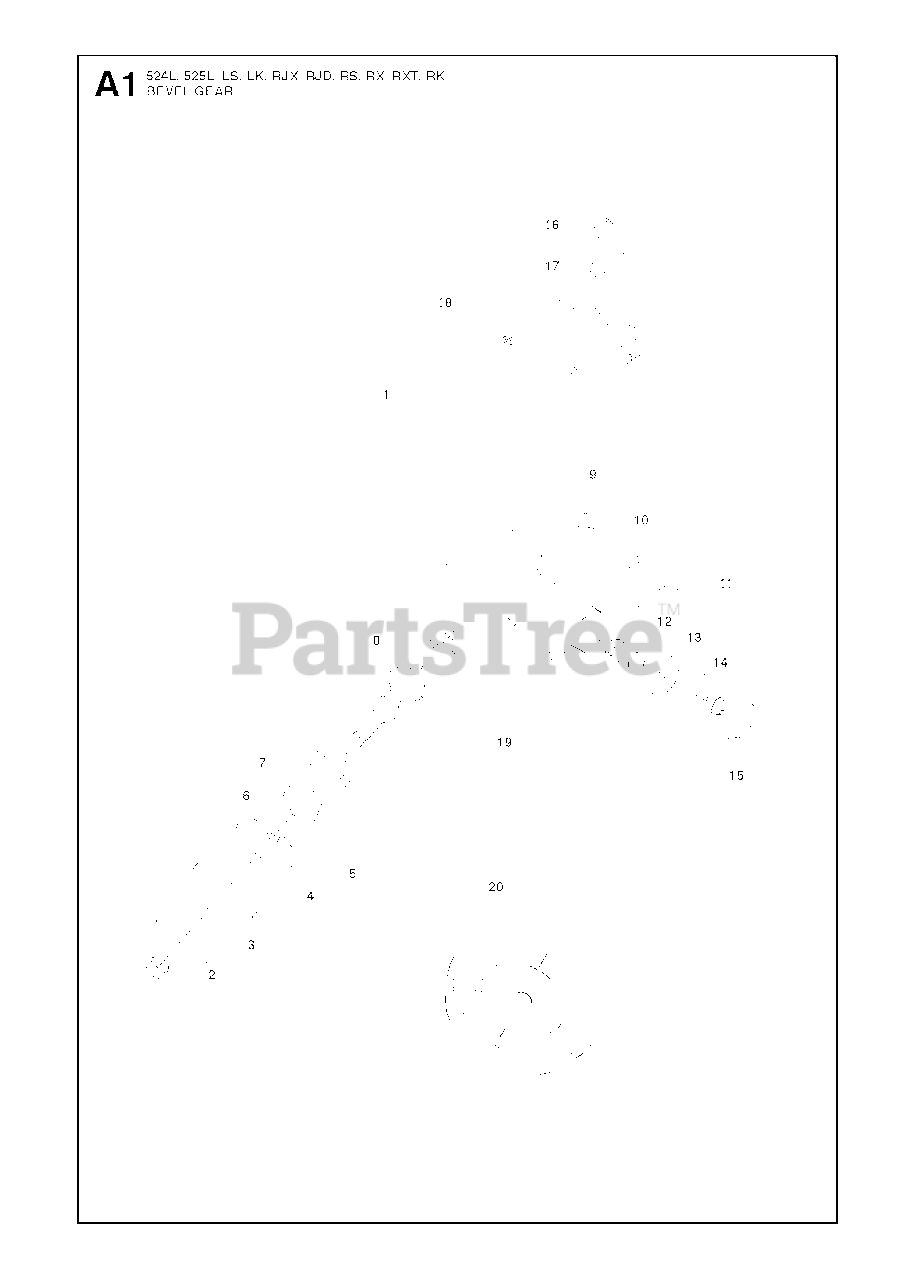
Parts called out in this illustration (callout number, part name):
1	GEAR HEAD
2	GEARHEAD NUT - BRUSHCUTTER
3	SUPPORT FLANGE
4	WASHER
5	DRIVE DISC
6	RETAINING RING SGH 28
7	BEARING
8	BALL BEARING 8X22X7/608Z
9	PLUG
10	SCREW
11	SCREW
12	BALL BEARING 24X9X1/609ZR
13	BEARING
14	RETAINING RING
15	RETAINING RING
16	SCREW ITXSCM
17	SCREW
19	GEAR SET
20	SUPPORTING CUP
